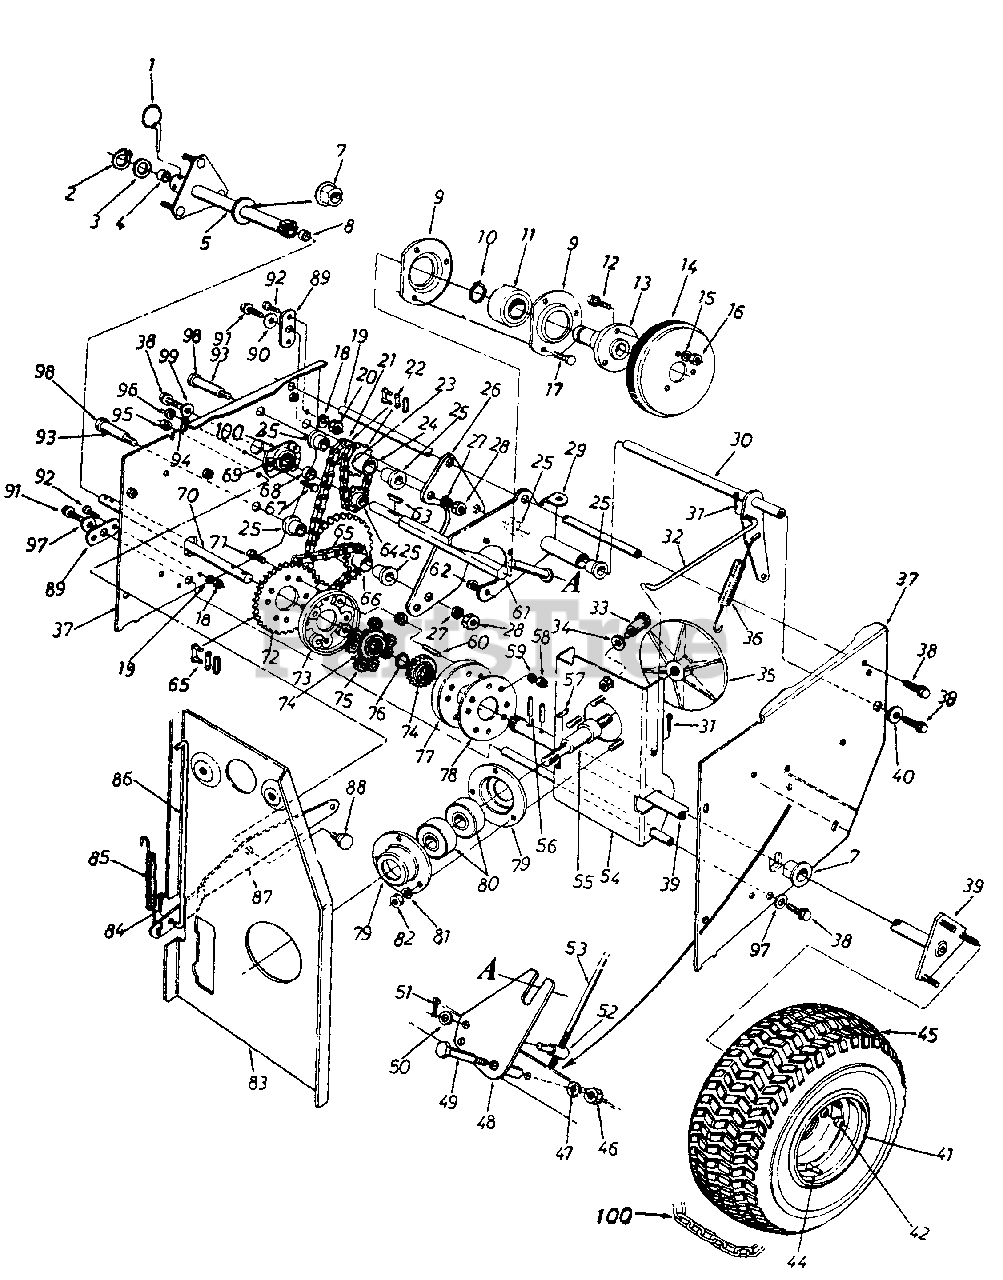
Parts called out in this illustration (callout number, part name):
1	Klick Pin 1/4" Dia. x 1.75"
2	Snap Ring .625" Shaft
3	Fl-Wash .62" I.D. x 1.25"
4	Sleeve Brg.
5	Differential Tubing Ass'y.- R.H.
7	Flange Brg. w/Flats 1" I.D.
8	Sleeve Brg.
9	Bearing Housing
10	Snap Ring - 1.00" Dia.
11	Ball Brg .25MM x 52MM x 15MM Thk.
12	Hex Sems Bolt 5/16-18 x .75" Lg.
13	Friction Wheel Adapter
14	Friction Wheel Ass'y.
15	L-Wash. 5/16" I.D.
16	Hex Nut 5/16-18 Thd."
17	Hex Bolt 1/4-28 x .62" Lg.
18	L-Wash. 1/4" I.D.
19	Sliding Support Axle
20	Hex Nut 1/4-20 Thd.
21	#41 Chain - 1/2" Pitch x 43 Links
22	Master Link
23	#41 Chain - 1/2" Pitch x 19 Links
24	9 and 14 Teeth Sprocket Hub Ass'y.
25	Flange Brg .630" I.D.
28	Hex L-Jam Nut 3/8-24 Thd.
29	Sliding Brkt. Ass'y.
30	Drive Clutch Brkt. Ass'y.
31	Inter. Cot. Pin 5/16" Dia.
32	Drive Clutch Rod 7.38" Lg.
33	Shld. Bolt
34	Bell-Wash .44" I.D. x .88"
35	Aluminum Drive Plate
36	Extension Spring 4.31" Lg.
37	Frame Ass'y.
38	Hex L-Bolt 5/16-18 x .62"
39	Differential Shaft Ass'y.
40	Fl-Wash .345" I.D. x .75"
41	Rim Only - 16"
42	Cone Nut 3/8-24 Thd.
44	Tubeless Air Valve
45	Wheel Ass'y. Comp. 16 x 6.5
46	Hex Jam Nut 3/8-16 Thd.
47	L-Wash. 3/8" I.D.
50	Fl-Wash .344" I.D. x .62"
51	Cotter Pin 3/32" Dia x .75"
52	Adjustment Ferrule
53	Shifting Rod
56	H-Spring Pin Spiral 3/16" Dia. x 1.25" Lg.
57	#61 Hi-Pro Key 3/16 x 5/8" Dia.
58	Hex Nut 1/4-28 Thd.
59	L-Wash 1/4" I D.
60	Differential Pin
61	Hex Shaft
62	Hex L-Nut 1/4-28 Thd.
63	#9 Hi-Pro Key 3/32 x 5/8" Dia.
64	8 Teeth Sprocket
65	#420 Chain - 50 Pitch x 37 Link
66	9 and 32 Teeth Sprocket Hub Ass'y.
67	Hex Bolt 1/4-20 x 62" Lg.
68	Spacer 51" I D x 69" 0 D.
69	Ball Bearing
70	Differential Connecting Shaft
71	Hex Bolt 1/4-28 x 1.75" Lg.
72	28 Teeth Sprocket
73	Differential Housing
74	20 Tooth Spur Gear
75	9 Tooth Spur Gear
76	Fl-Wash. 62" I.D x 1.25"
77	Differential Housing
78	Differential Hsg. Support Plate
79	Bearing Housing
80	Ball Brg .787" I.D. x 1 85"
81	L-Wash 5/16" I.D.
82	Hex Nut 5/16-18 Thd
83	Engine Brkt Ass'y
84	Inter. Cotter Pin 5/16" Dia
85	Extension Spring 3.18" Lg.
86	Auger Clutch Rod 31" Dia x 10.62" Lg
87	Auger Clutch Brkt.
88	Shld Bolt .625" Dia x 170"
89	Pivot Axle Brkt.
90	Fl-Wash. 345" I.D. x .75"
91	Hex L-Bolt 5/16-18 x .62"
92	Hex Bolt 1/4-20 x .62" Lg."
93	Sprocket Hub Tubing 1.88"
94	L-Wash 1/4" I.D.
95	Hex Cent L-Nut 3/8-16 Thd.
96	Hex Nut 1/4-20 Thd
97	Fl-Wash .344" I.D. x .875"
98	Hex Bolt 3/8-24 x 2.75" Lg
99	Bell-Wash .345" I.D. x .88"
100	Tire Chain
